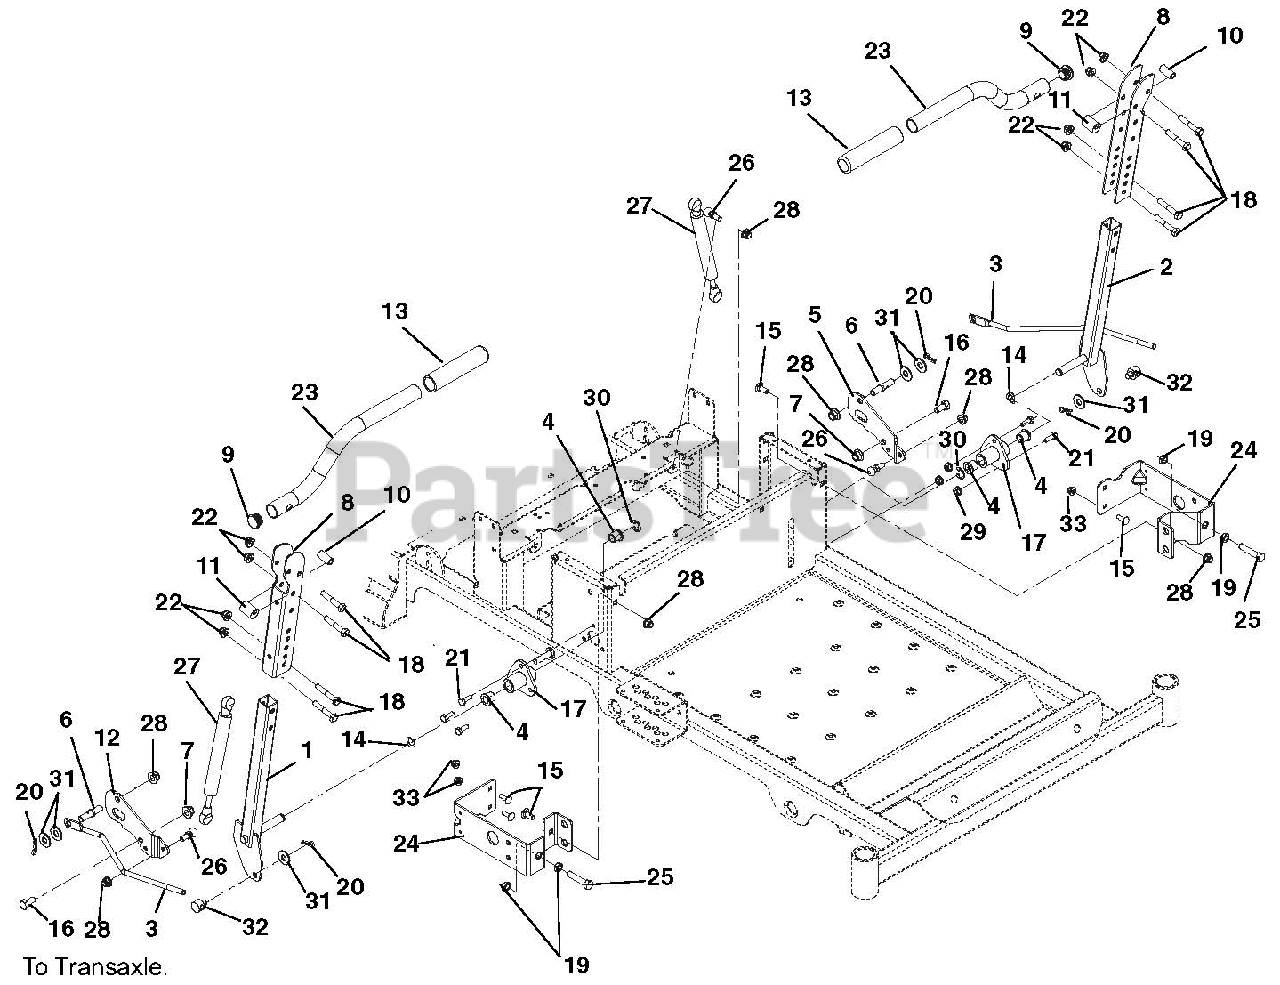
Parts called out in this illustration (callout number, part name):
1	WMT, RH CONTROL ARM
2	WMT, LH CONTROL ARM
3	LINK, STEERING
4	BSHG, FLG .500X.625.620X.857
5	PLATE, DAMPER (LH)
6	PIN, TRANS
7	@NUT-LK-NYL-FLG .38-16 YWZC
8	CHANNEL, UPPER HANDLEBAR
9	CAPLUG, HANDLEBAR
10	BSHG, SPCR .330X.500X1.01 PM
11	BSHG,ECCEN .328X.750X1.01 PM
12	PLATE, DAMPER RH
13	GRIP - HANDLEBAR
14	WSHR-WAVE .50X.75X.015 .13FRHT
15	@BLT-RHDSSQNK .31-18X.75 G5YZ
16	@BLT-HEX .38-16X.75 GR5 YWZC
17	BUSHING, FLANGED
18	BLT-HEX .31-18X1.75 GR5 PDB
19	NUT-HEX-JAM .375-16 YWZC
20	PIN-HAIR INT .08X.18X1.18 YWZC
21	@BLT-HEX .25-20X.75 GR5 YWZC
22	NUT, .31-18 NYLOC FLANGE PDB
23	HANDLE, STEERING
24	BRKT, SPEED ADJ/SEAT PIVOT
25	BLT-HEX .375-16X1.750 FTD YWZC
26	STUD- BALL
27	DAMPER
28	@NUT-LK-NYL-FLG .31-18 YWZC
29	@NUT-LK-TOP-FLG .25-20 YWZC
30	RG-RTNG-EXT .500X.042 (E)
31	@WSHR-FL-STL.438X1.00X.083 YWZ
32	TRUNNION, BRAKE .31-18 UNC
33	@NUT-LK-NYL-FLG .25-20 YWZC
